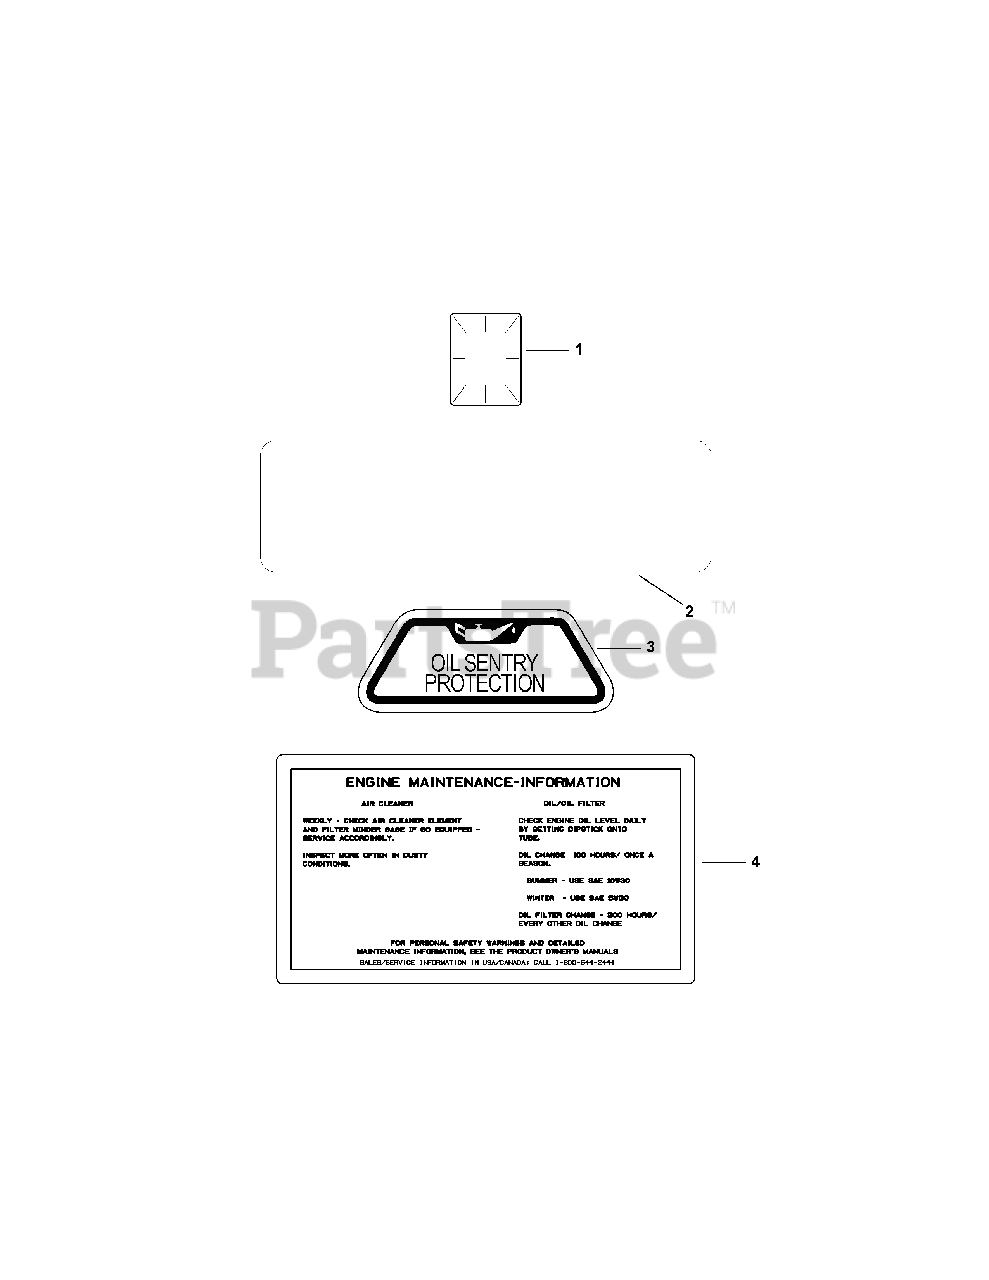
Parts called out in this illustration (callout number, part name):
1	DECAL, CLEAR LAMINATE
2	DECAL, COMMAND 27 HP
3	DECAL, OIL SENTRY
4	DECAL, AIR CLEANER
